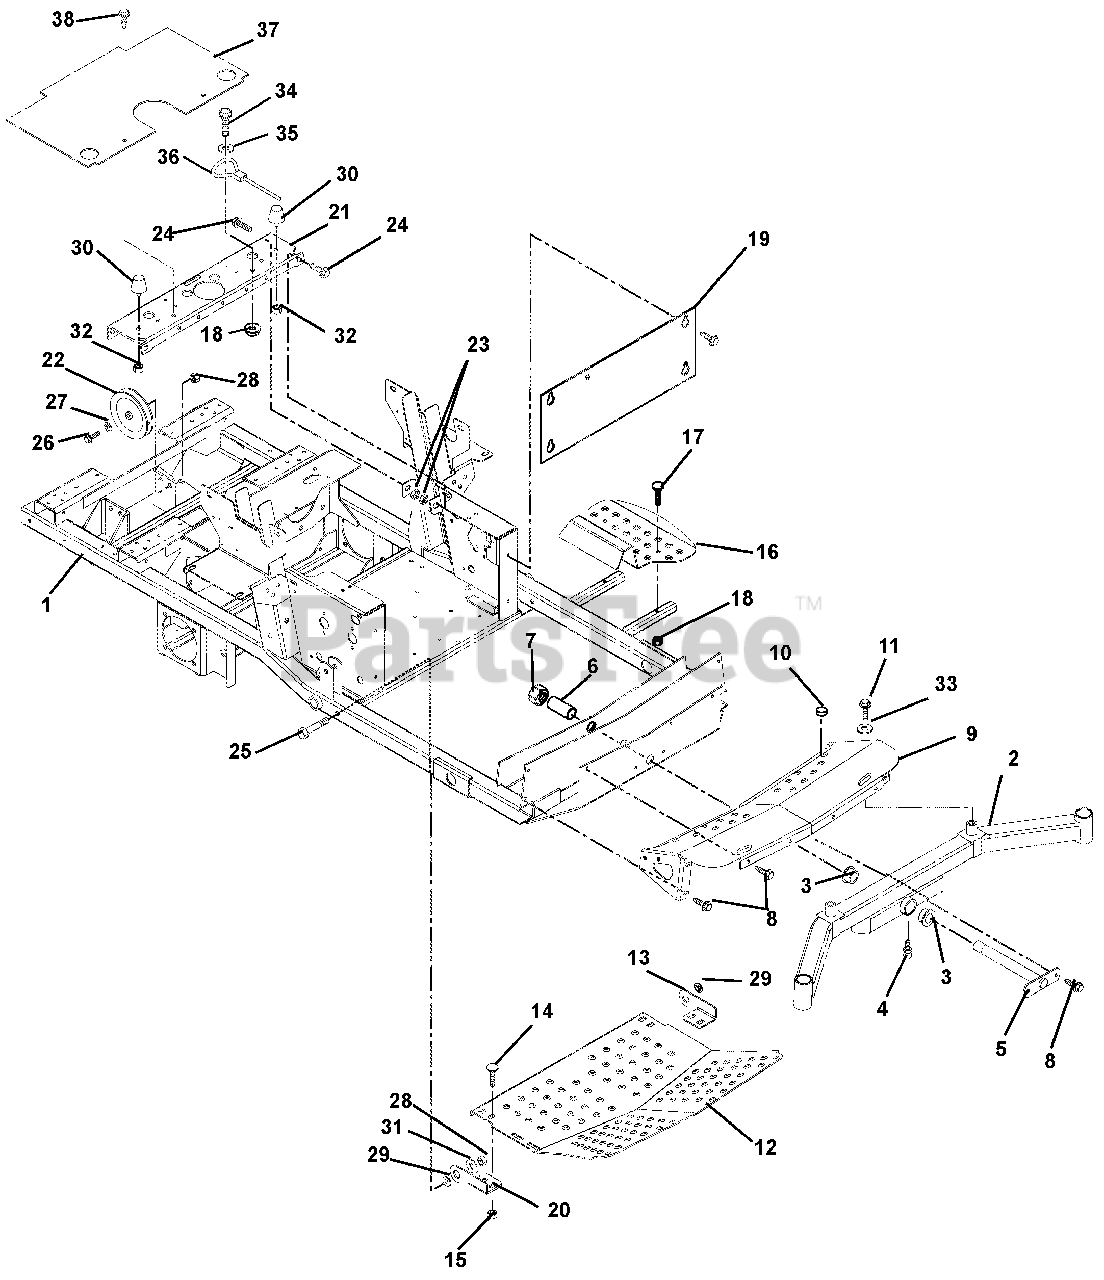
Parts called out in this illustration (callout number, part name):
1	Weldment, Frame
2	Weldment, Front Axle
3	Bushing, Flange 1.020 x 1.385 x .75 x 1.75
4	Fitting, Lube .25-28 x .256
5	Pin, Axle
7	Nut, Locking Nylon 1.0-14
8	Screw, Tapping .38-16 x .75
9	Weldment, Axle Cover
10	Button, Bumper
11	Bolt, Hex .50-20 x 1.00 Grade 5
12	Panel, Inspection
13	Hinge, Footboard Left Hand
14	Bolt, Round Head Square Neck .38-16 x 1.00 Grade 5
15	Nut, Locking Top Flange .38-16
16	Step, Ingress
17	Bolt, Round Head Square Neck .31-18 x 1.75 Grade 5
18	Nut, Locking Top Flange .31-18
19	Plate, Kick
20	Hinge, Footboard Right Hand
21	Channel, Cross
22	Pulley, Idler
23	Nut, Retainer .375-16 x .37
24	Bolt, Serrated Flange Washer Head .38-16 x 1.00
25	Bolt, Hex .50-13 x 3.25 Grade 5
26	Bolt, Hex .50-13 x 2.25 Grade 5
27	Washer, Flat Steel .505 x .88 x .072
28	Nut, Locking Top Flange .50-13
29	Bushing, Flange .515 x .75 x .275 x 1.12
31	Washer, Flat Steel .563 x 1.38 x .109
32	Nut, Locking Flange .312-24
33	Washer, Flat Steel .064 x 1.810 x .250
34	Bolt, Hex .31-18 x .75 Grade 5
35	Washer, Flat Steel .328 x 1.00 x .094
36	Cable, Seat Prop
37	Guard, Grass
38	Screw, Tapping .38-16 x .50 Hex Washer Head Thread Rolling
